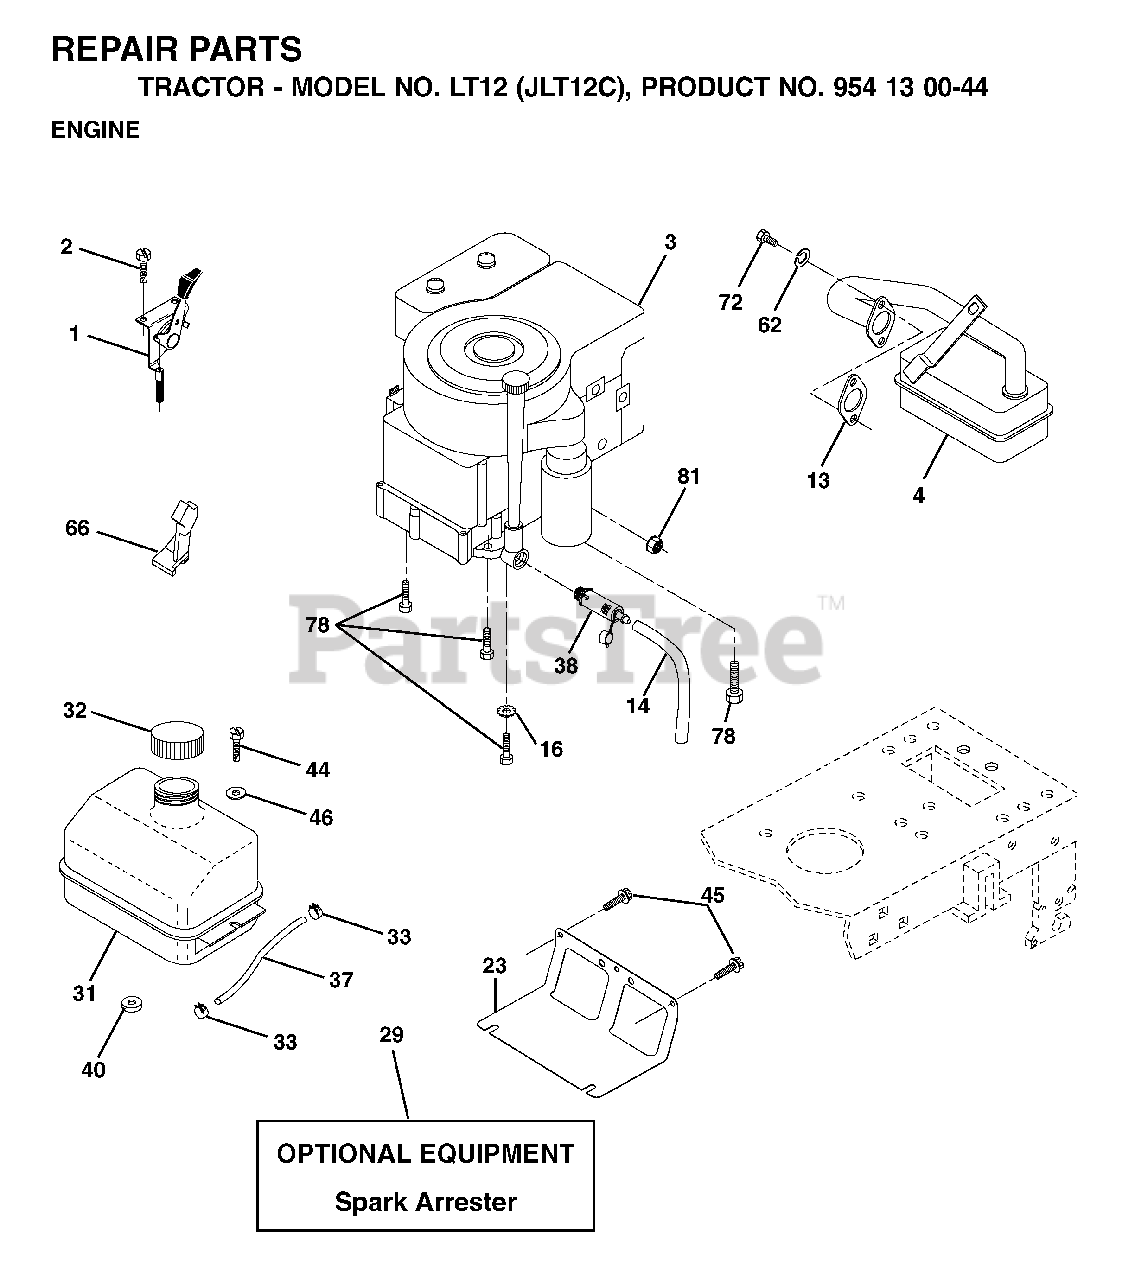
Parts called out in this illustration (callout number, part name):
1	THROTTLE CONTROL CABLE
2	SCREW LT
13	REPL BY 532 27 22-93
14	TUBE, DRAIN OIL ASM.
16	LOCKWASHER
23	SHEILD.BROWNING.DBR.GUARD
29	ARRESTER SPARK (OPTIONAL)
32	FUEL CAP
33	HOSE CLAMP
37	LINE.FUEL.20
38	PLUG, OIL DRAIN EASY
40	GROMMET T
44	SCREW HEXWSHR 1/4-20X3/4
45	SCREW, 3/8-16X3/4
62	LOCKWASHER
66	STOP THROTTLE
72	SCREW
78	SCREW.3/8-16
81	NUT
